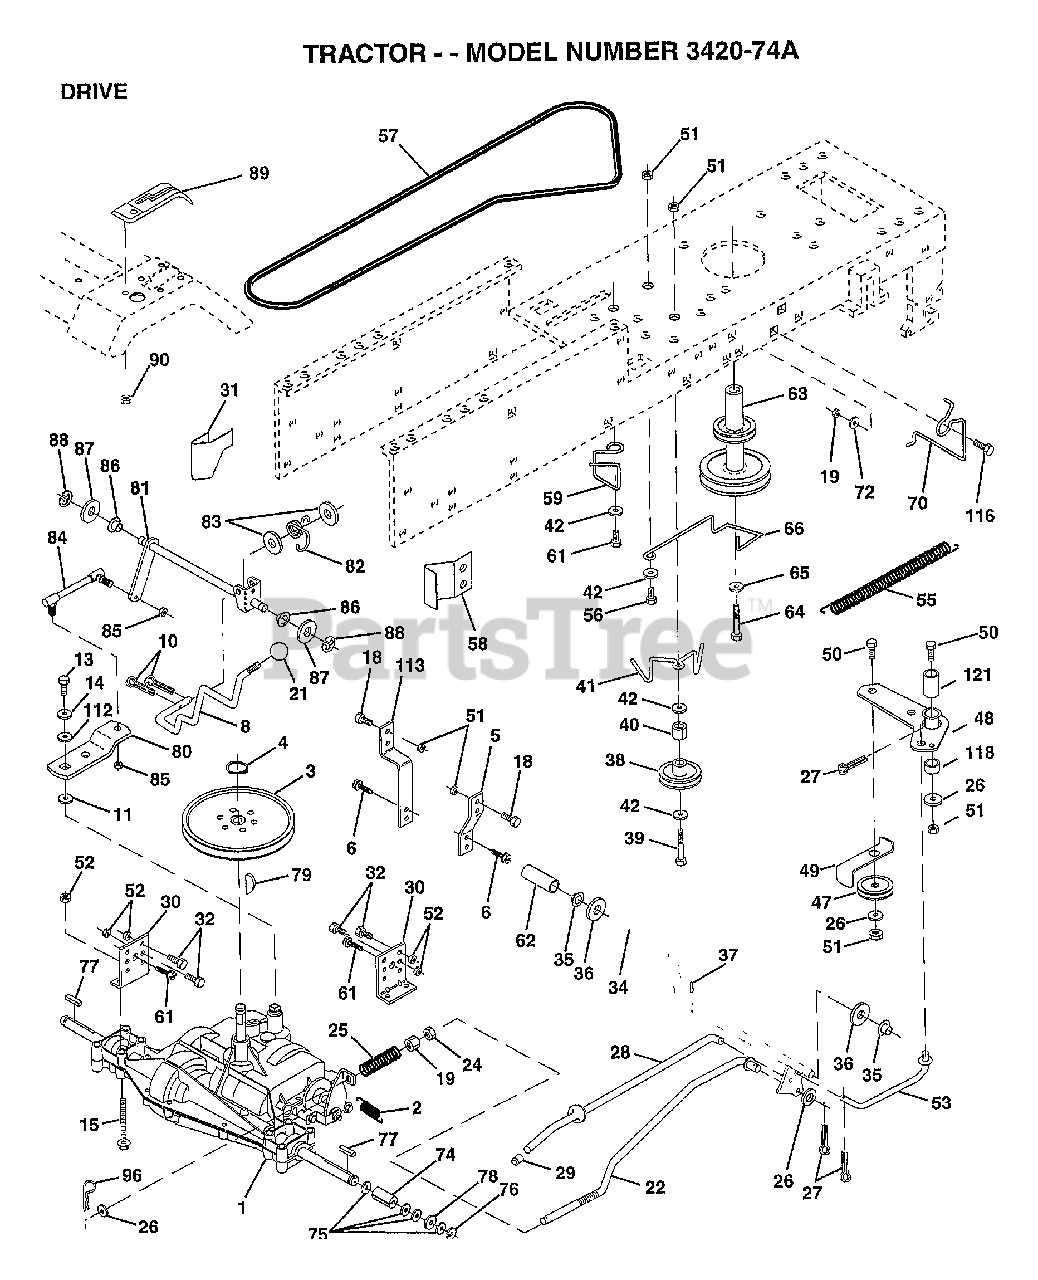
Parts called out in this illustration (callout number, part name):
1	TRANSAXLE, PEERLESS
2	SPRING.BRAKE.RETU
3	PULLEY TRANS
5	STRAP TORQUE
6	SCREW
8	ROD SHIFT FEND LT
10	PIN COTTER 1/8
11	WASH-SHFT PLT LT
12	WASHER
13	BOLT.1/4-28.W/PAT
14	LOCKWASHER
15	BOLT.HX.FLG.5/16
18	BOLT
19	NUT
21	KNOB T (1/2-HOLE)
22	BRAKE ROD
24	NUT
25	SPRING ROD LT
26	WASHER
27	COTTER PIN
28	ROD.BRAKE.PARK.LT
29	PLUNGER CAP T
30	TRANSAXLE MTG BKT
31	"KEEPER,BELT LH T"
32	BOLT
34	SHAFT ASM-PEDAL F
35	NYLON BEARING
36	WASHER LT
38	PULLEY.IDLER.FLAT
39	BOLT
40	SPACER T
42	WASHER
48	BELLCRANK ASM
49	RETAIN BELT
53	"LINK, CLUTCH T"
55	"SPRING, RETURN LT"
58	"KEEPER,BELT RH T"
59	KEEPER BELT CNTSP
61	SCREW
62	PEDAL COVER T
63	PULLEY.ENGINE
64	BOLT
65	LOCKWASHER
66	KEEPER-BELT
70	KEEPER BELT ENG
72	WASHER
74	SPACER AXLE
75	WASHER
76	E-RING LT
77	SQUARE KEY
78	WASHER
80	"ARM.SHIFT.20""TIRE"
81	SHAFT.CROS.P930.
82	"SPRING,TORSION"
83	WASHER
84	"ROD.TIE.20""P930LT"
85	NUT.CNT.LOCK.1/4
86	BUSHING
87	WASHER D
88	KLIP RING
90	NUT
96	RETAINER M
112	WASHER LT
113	"STRAP,TORQUE"
116	BOLT RDHD 3/8-16
118	SPACER-BELLCRANK
121	NYLINER-CLUTCHING
